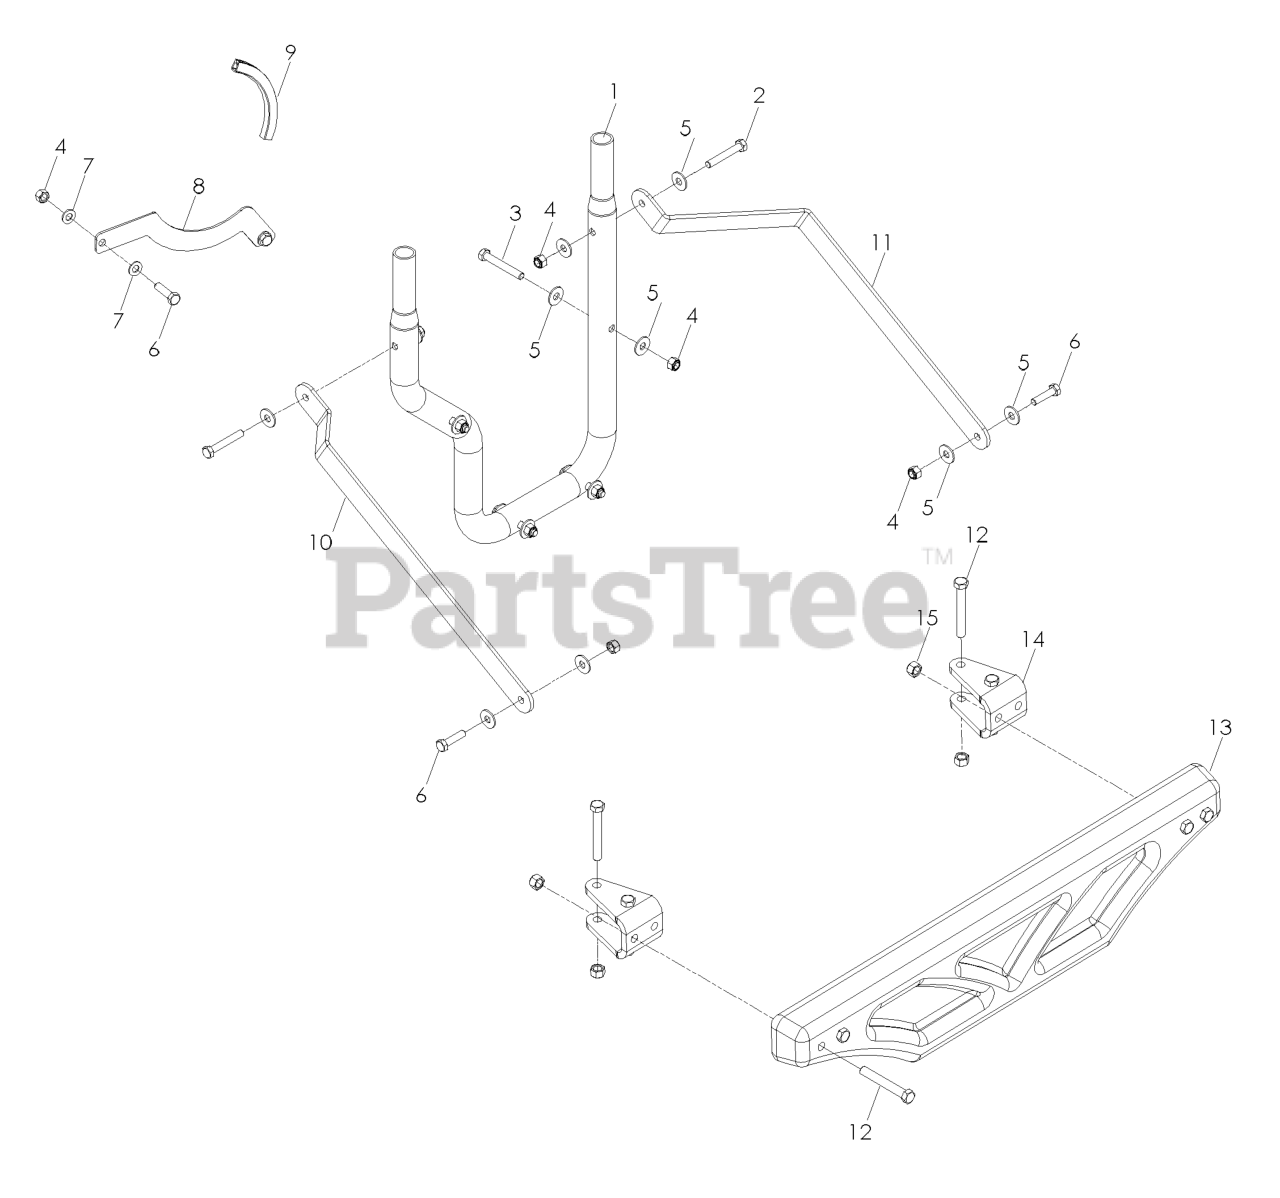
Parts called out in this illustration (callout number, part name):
1	MOUNT.TUBE.COLLECTIONS
2	HCS 5/16-18X2
4	NUT 5/16 NYLOC
5	WASHER 5/16 FLAT
6	HCS 5/16C X 1 1/4
7	FLAT WASHER 5/16 SAE
8	SUPPORT.CHUTE.COLLECTION.BLACK
9	RP.FLEX TRIM, BLK-LENGTH 1 FT
12	SCREW 3/8C X 2 3/4 HEX CAP
13	CAST WEIGHT
14	WEIGHT BRACKET, BLACK
15	NUT 3/8-16 NYLOC
